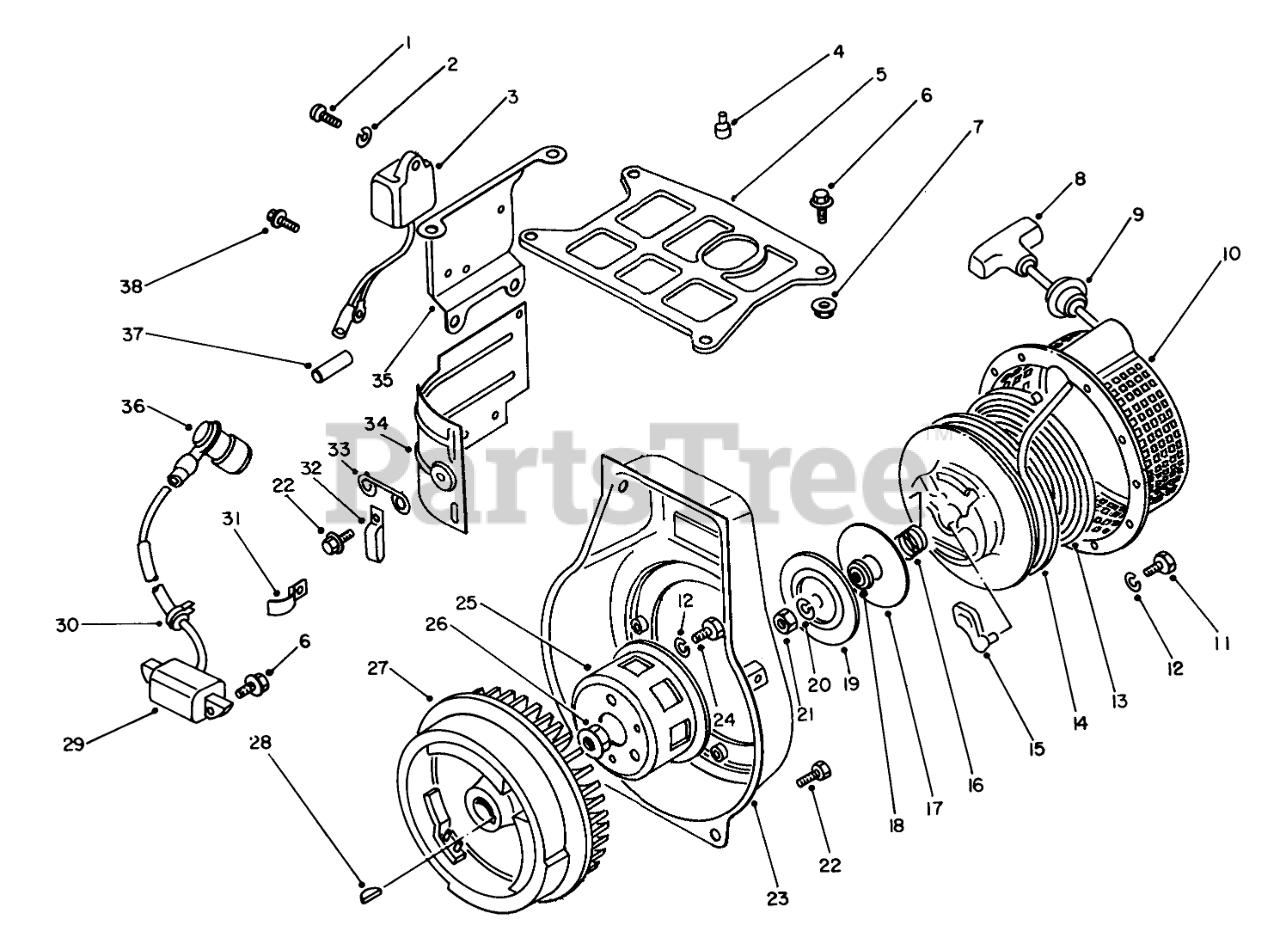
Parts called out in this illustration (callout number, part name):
1	Screw
2	Washer
3	Transistor Magnet
4	Cushion
5	Cowling-Upper
7	M6 X 1 LOCKNUT
8	Grip
9	Grip Assembly (Incl. Ref. #8)
10	Starter Assembly (Incl. Ref. #13-21)
12	Lockwasher
13	SPRING
15	Ratchet
16	Spring
17	Plate-Slide
18	Cover
19	Plate
20	WASHER-LOCK
23	COVER
25	STARTER PULLEY
27	ROTOR ASM
29	STARTER ASM
30	Grommet
31	Clamp
32	Clamp
33	CLAMP
34	COWLING
35	Bracket
36	SPARK PLUG CAP
38	SCREW-HHF
